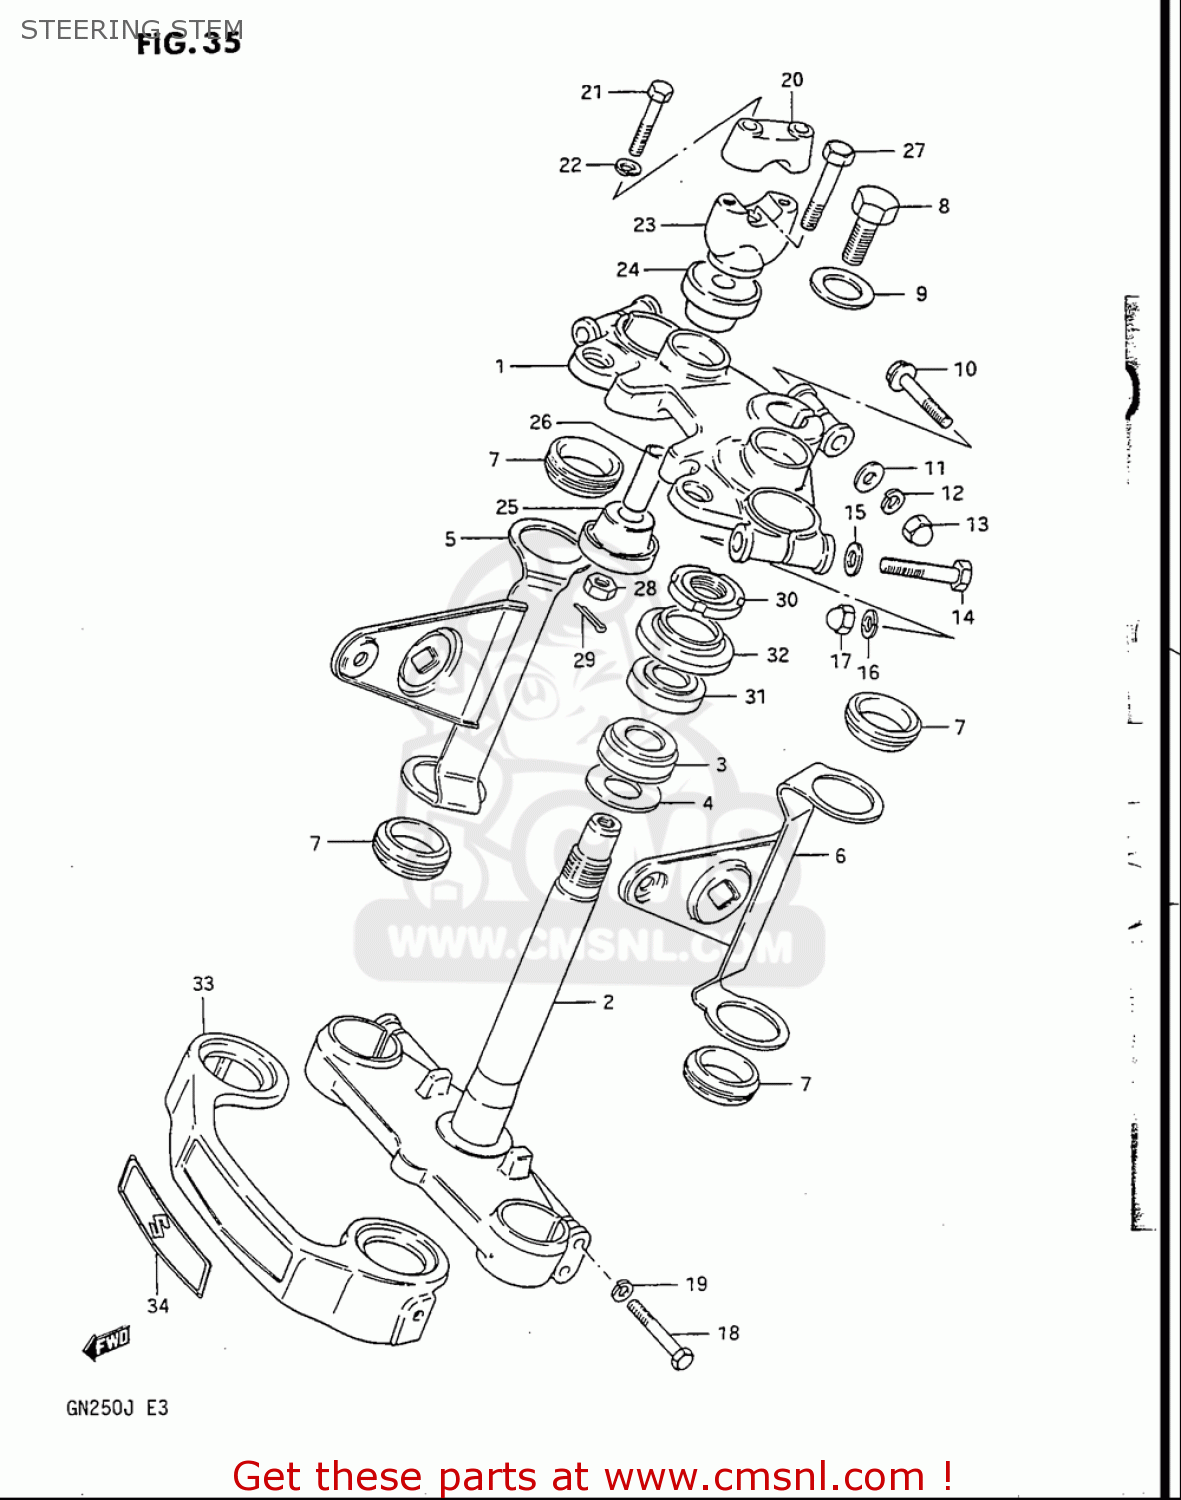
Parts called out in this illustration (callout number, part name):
1	HEAD,STEERING STEM
2	STEM SET,STEERING
3	BEARING(30X55X17)
4	SHIM(30X40X1.5)
5	BRACKET,HEADLAMP,R
6	BRACKET,HEADLAMP,L
7	CUSHION,HEADLAMP BRACKET
8	BOLT(12X20)
9	WASHER (12.5X26X1.6)
10	BOLT
11	WASHER
12	WASHER,LOCK
13	NUT
14	BOLT
15	WASHER
16	WASHER,LOCK
17	NUT
18	BOLT
19	WASHER,LOCK
20	HOLDER,HANDLE UPR
21	BOLT
22	WASHER,LOCK
23	HOLDER,HANDLEBAR LWR
24	CUSHION,UPR
25	CUSHION,LWR
26	SPACER(10.2X14X46)
27	BOLT(10X78)
28	NUT
29	COTTER PIN
30	NUT,STEERING STEM(25X44X10)
31	BEARING(25X47X15)
32	SEAL,STEERING UPR DUST
